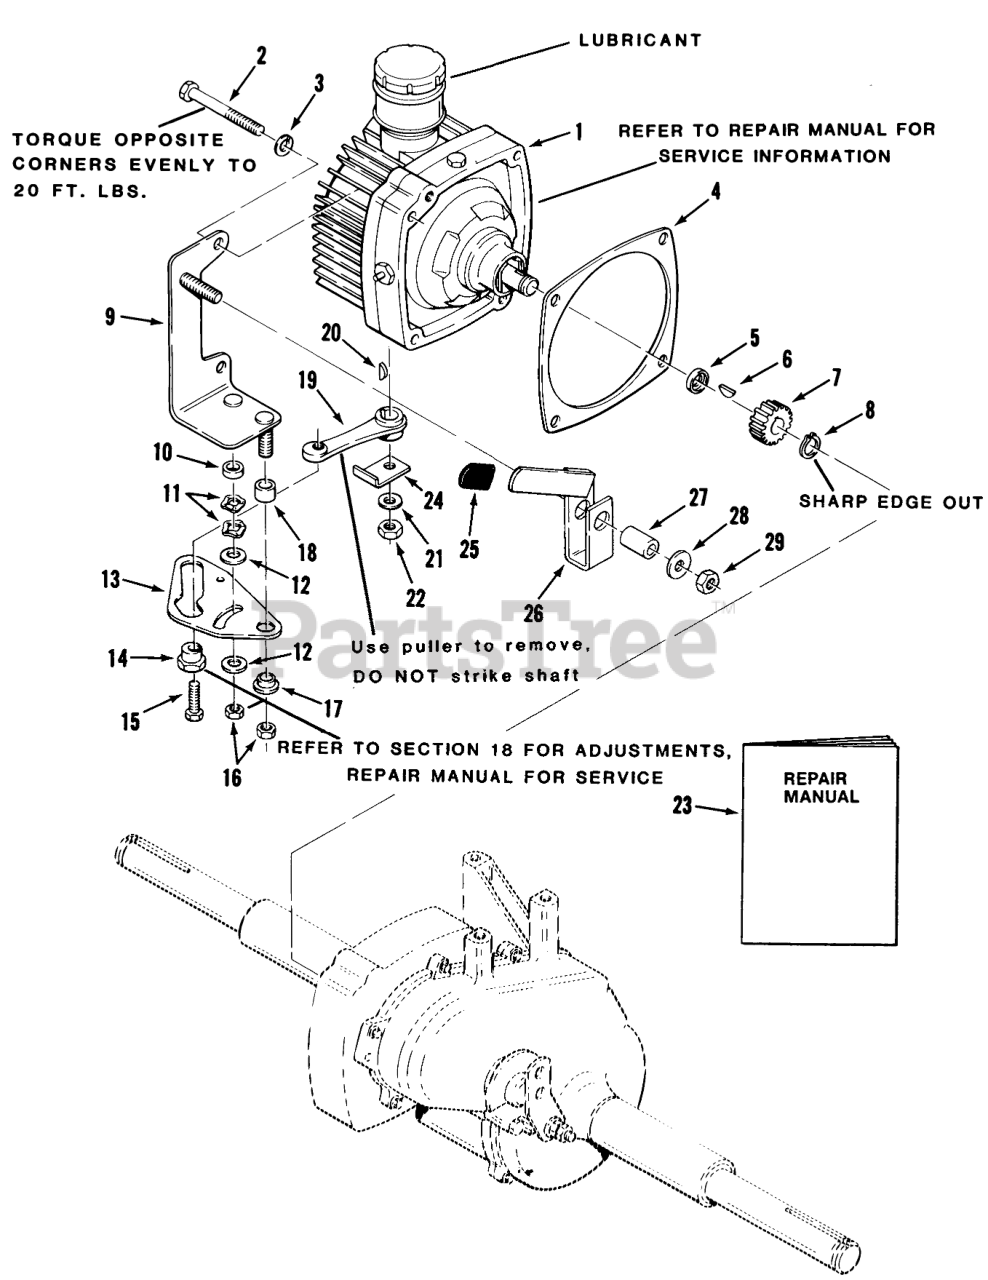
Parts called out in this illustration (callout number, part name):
1	Pump & Motor (219024-Rebuilt)
2	Bolt 3/8-16 X 3
3	Lockwasher 3/8
4	Gasket
5	Spacer
6	Woodruff Key 1/8 X 1/2
7	Gear 12 Tooth
8	Snap Ring
9	Control Plate
10	Spacer (Short)
11	Washer-Spring
12	Washer-Friction
13	Cam-Speed Control
14	Eccentric Cam
15	Eslok Bolt 5/16-18 X 1
16	Lock Nut 3/8-16 Hi-Tensile
17	Spacer
18	Spacer (Long)
19	Cam Follower Arm
20	Woodruff Key 1/8 x 1/2
21	Washer 3/8 SAE
22	Eslok Nut 3/8-16
23	Automatic Trans. Repair Parts & Service Manual
24	STOP-CAM
25	GRIP
26	ASS'Y-DUMP VALVE B
27	SPACER
28	Washer
29	NUT-HEX, JAM
